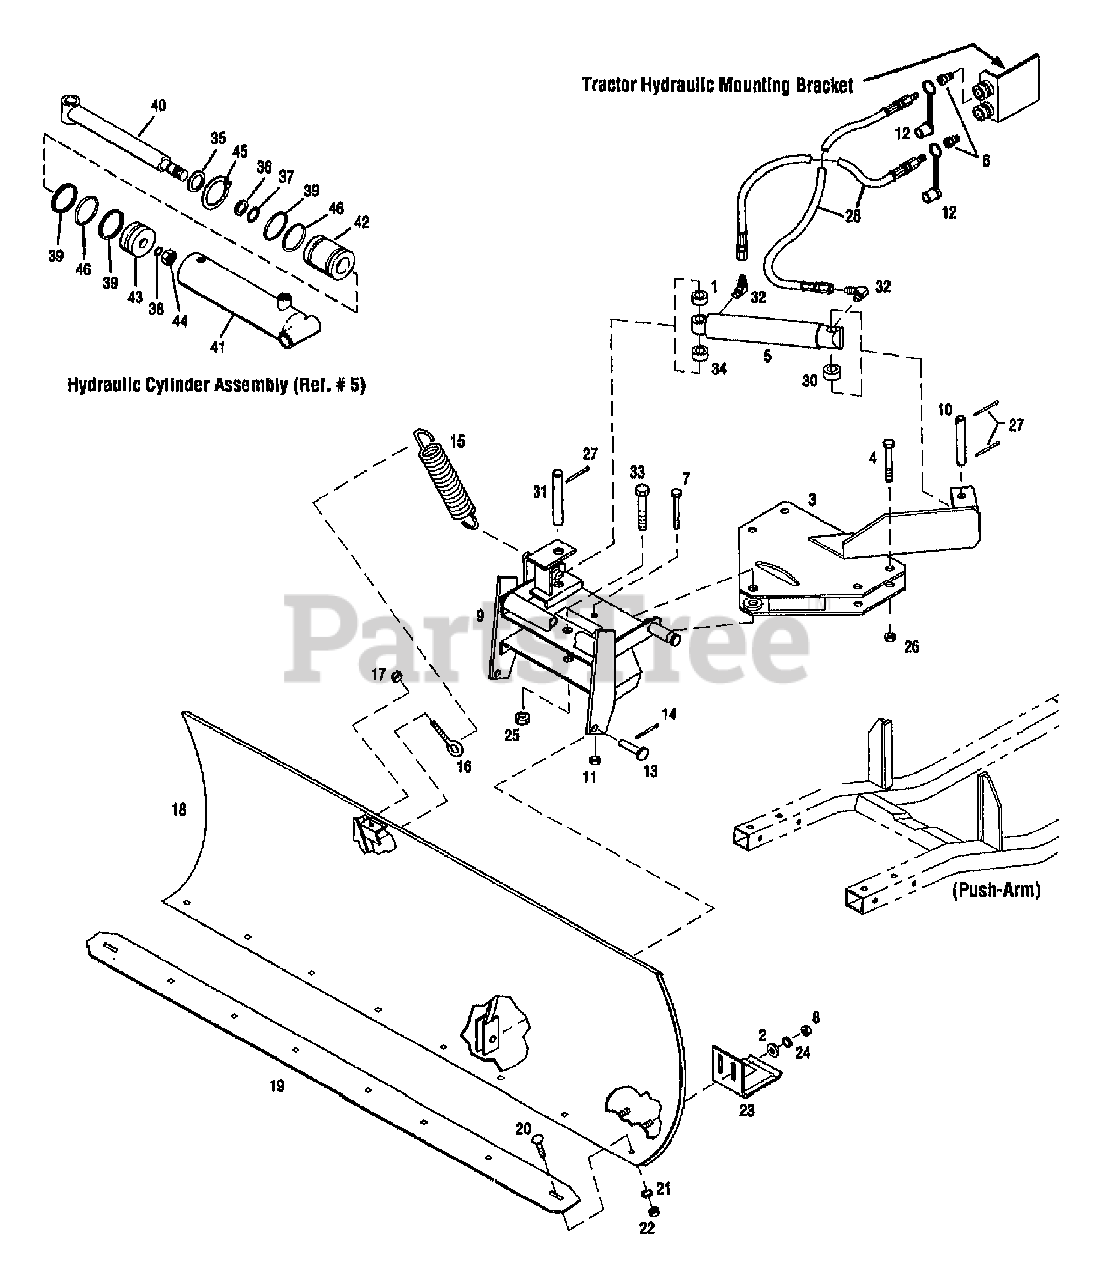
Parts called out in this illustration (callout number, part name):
1	SPACER-1.0X.781X.5
2	WASHER-FLAT 3/8 SAE
3	HITCH-SNOWBLADE
4	SCR-HH 1/2-13X2.5 G5 ZP
5	ASSM-CYL HYDRAULIC
6	COUPLING-HYDRAULIC
7	SCR-HH 3/8-16X3.0 G5 ZP
8	NUT-HEX 3/8-16 ZP
9	PLATE-PIVOT
10	PIVOT-PIN
11	NUT-LOCK 3/8-16
13	PIN-CLEVIS .5X1.06 ZP
14	PIN-COTTER .125 X .75 ZP
16	BOLT-EYE 5/16-18X2.75 ZP
17	NUT-TOP/LK 5/16-18 ZP
19	BLADE-SCRAPER
20	SCR-CARR 5/16-18X1.0 G2 ZP
21	WASHER-LK .312 ZP
22	NUT-HEX 5/16-18 ZP
23	SHOE-SKID
24	WASHER-LK .375 @ DEPL
25	NUT-LOCK
26	NUT-TOP LOCK 1/2-13 ZP
27	PIN-COTTER .120X1.25 ZP
28	ASSM-HOSE HYDRAULIC
30	SPACER-1.0X781X.94
31	PIVOT-PIN
32	ELBOW-90 DEG
33	SCR-HH 5/8-11X3.0 G5
34	SPACER-1.0X.781X.61
35	SEAL-OIL
36	RING-BACK/UP
37	RING-O .984 ID
38	RING-O .424 ID
39	RING-BACK/UP
40	ROD-PISTON HYDRAULIC
41	TUBE-CYLINDER HYDRAULIC
42	HEAD-CYLINDER
43	PISTON-HYDRAULIC
44	NUT-H/LK 5/8-18
45	RING-RETAIN INT 2.210 DIA
46	RING-O 1.6 ID
